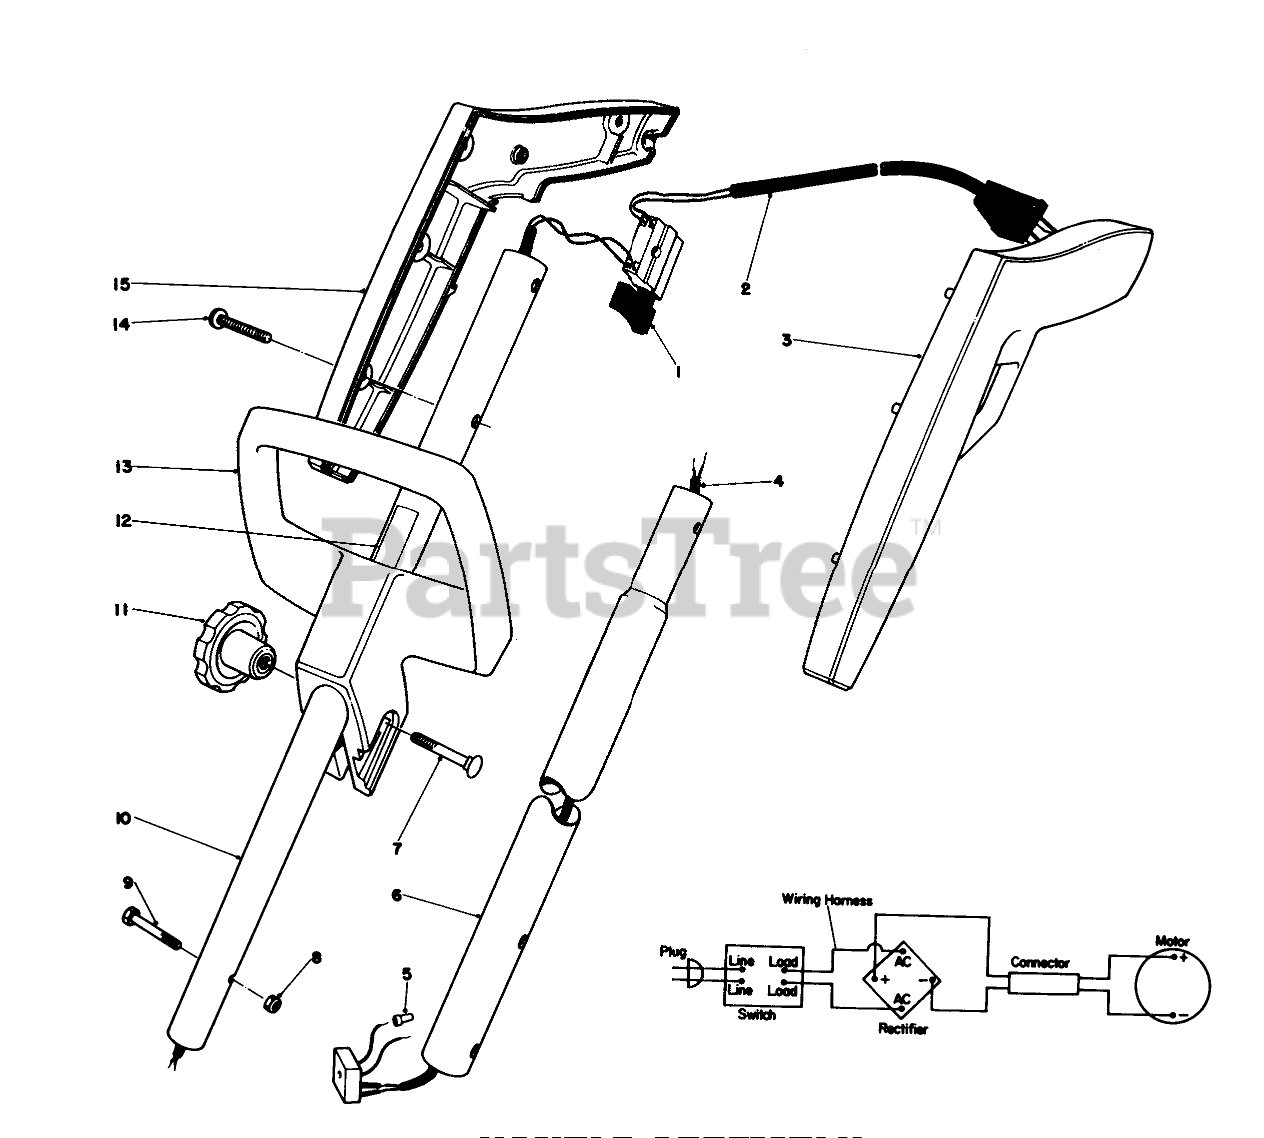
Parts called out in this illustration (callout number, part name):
1	SWITCH SINGLE SPEED
2	Power Cord
3	Grip L.H.
4	Wiring Harness w/Rectifier
5	Wire Connector
6	Tube-Lower
7	BOLT-CARR
8	NUT-LOCK, NI
9	HEX HD MACHINE SCREW
10	Tube-Upper
12	Decal-Caution
13	ADJUSTABLE HANDLE
14	Screw
15	R.H. GRIP
